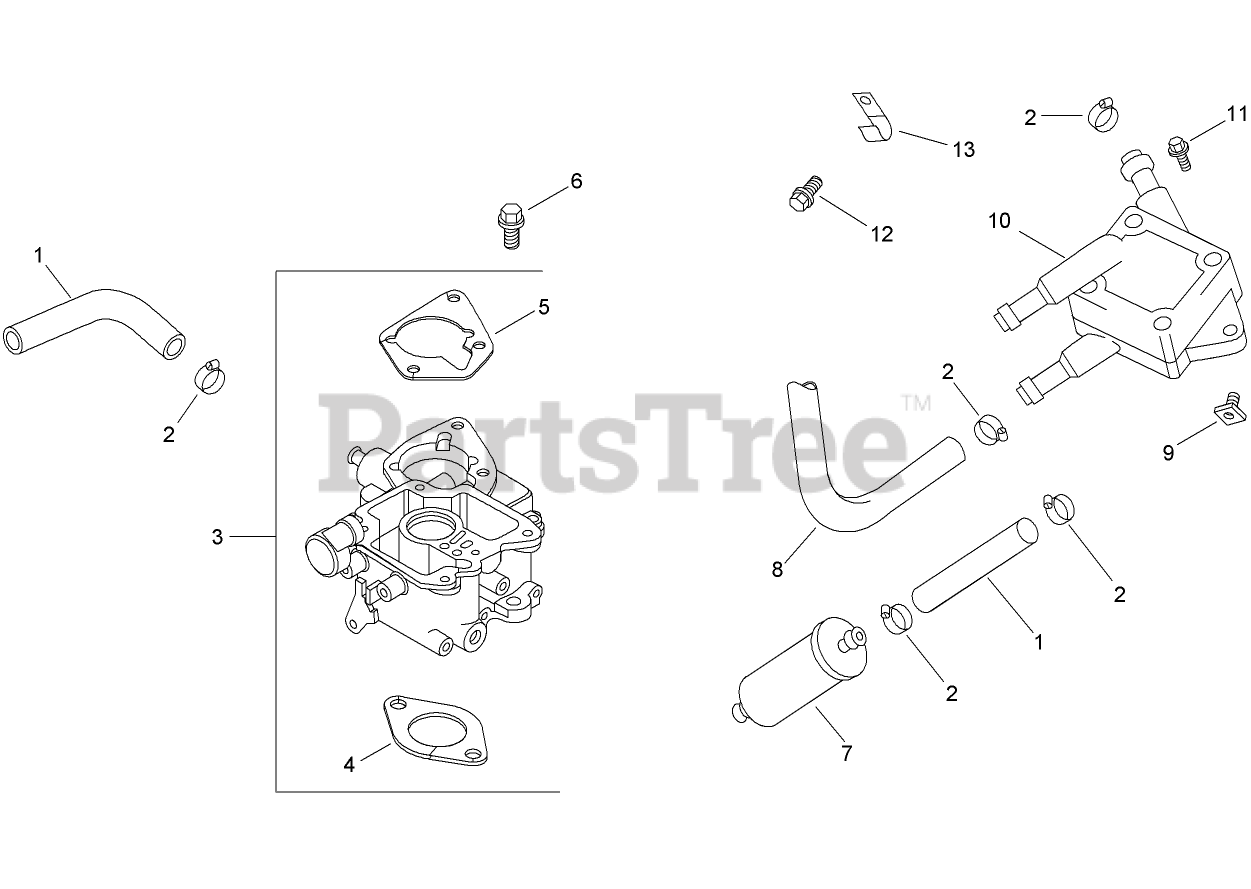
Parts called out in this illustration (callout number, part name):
1	LINE-FUEL (24.0 CUT TO LENGTH)
2	CLAMP-HOSE, SPRING (1/2)
3	Carburetor Kit (INCLUDES 4, 5)
4	GASKET-CARBURETOR
5	GASKET-BASE, AIR CLEANER
6	SCREW-FLANGE (M6X1.0X25)
7	FILTER-FUEL
8	Line-Fuel, Flexible (15.5)
9	Nut-Plastic
10	PUMP-FUEL
11	SCREW-TAP (M6X1.7X18)
12	Screw-HF (M6x1.0x12)
13	CLIP-CABLE
